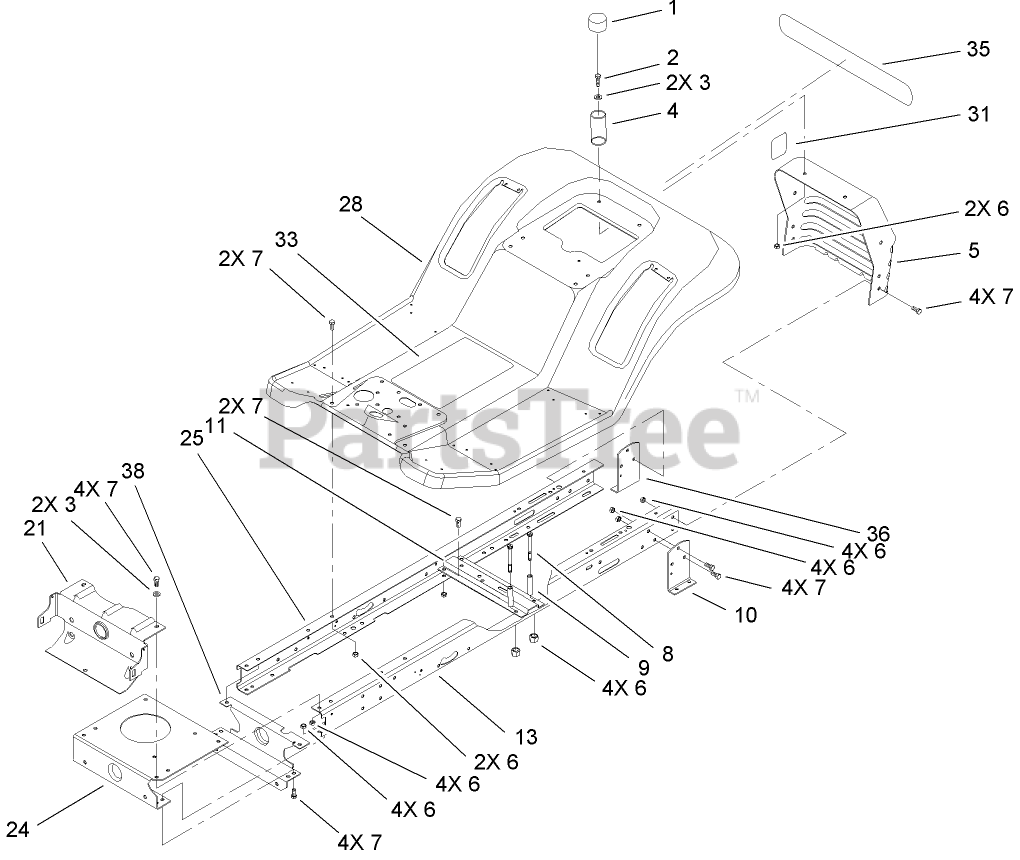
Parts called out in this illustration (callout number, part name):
1	CAP-PROTECTOR
2	SCREW-HH
3	WASHER-PLAIN
4	SPRING-COMPRESSION
5	SUPPORT-SEAT/REAR HITCH
6	NUT-LOCK, NI
7	SCREW-HH
8	SCREW-HH
9	SPACER
10	BRACKET-MOUNTING, LH TRANSAXLE
11	BRACKET-IDLER PIVOT
13	RAIL-FRAME, LH
21	SUPPORT-AXLE, FRONT
24	PLATE-MOUNTING, ENGINE
25	RAIL-FRAME, RH
28	REAR BODY ASM
31	DECAL-VALVE, DUMP
33	DECAL-INSTRUCTION
35	DECAL-REAR FENDER, LAWN TRACTORS
36	BRACKET-MOUNTING, RH TRANSAXLE
38	SUPPORT-REAR
